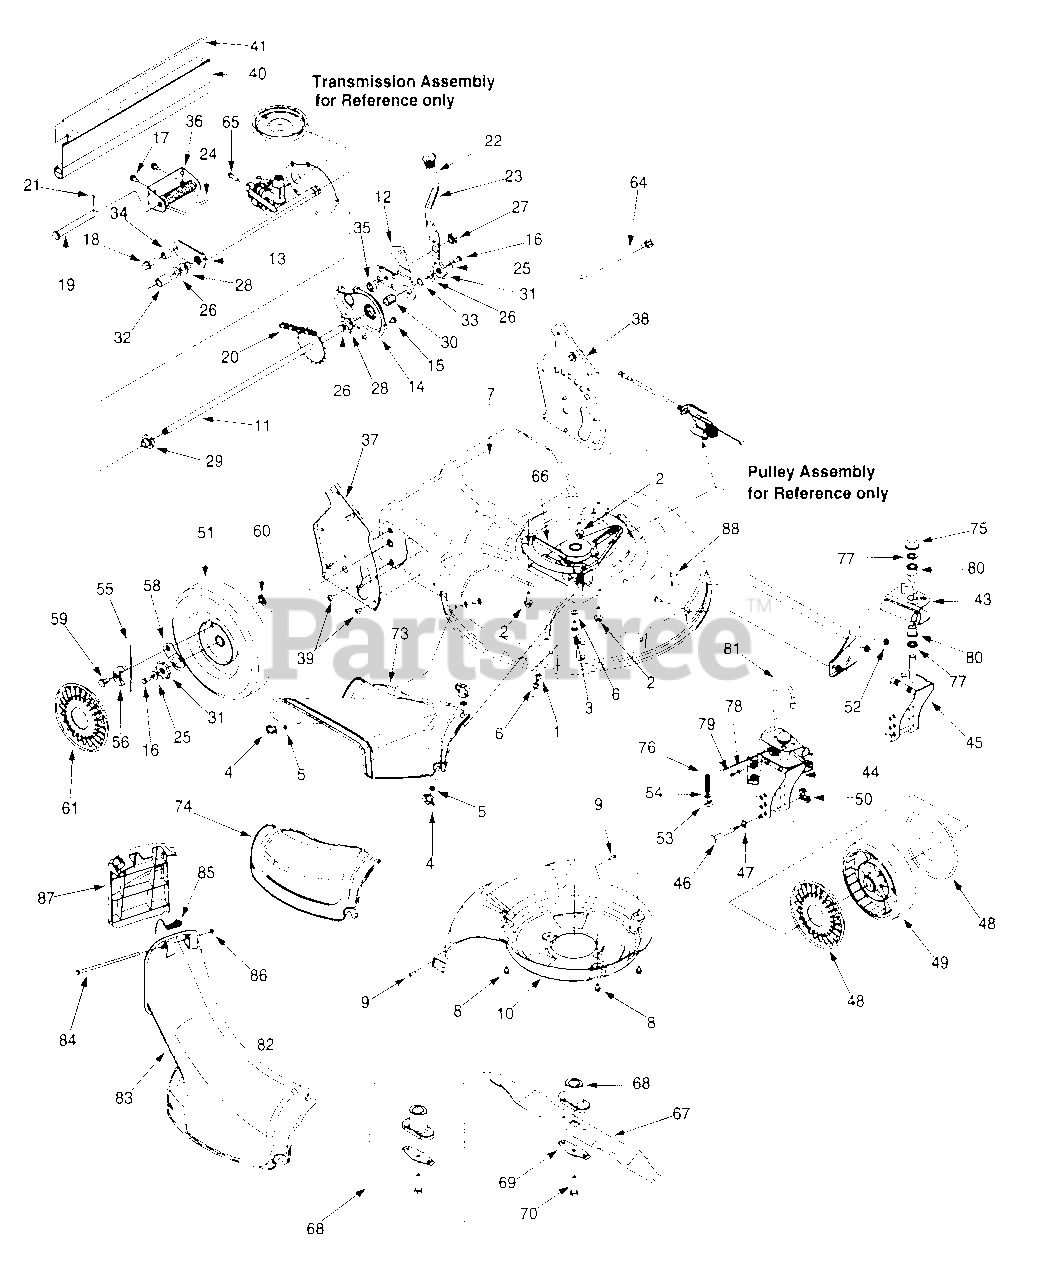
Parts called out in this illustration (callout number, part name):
1	Carriage Screw 1/4-20 x .62
2	Screw TT:3/8-18:1.00
3	Carriage Screw 1/4-20 x .750
4	Wing Nut 1/4-20
5	Push Nut .25 I.D. x .50 O.D.
6	Flat Washer .334 I.D.x .62 x.03
8	Screw TT. 1/4-20 x .375
9	Screw HL. 1/2-14 x .750
10	Baffle
11	Rear Axle Assembly
16	Cap Screw HH 1/4-20 x .620
17	Screw AB 1/4-20 x .625
18	Screw 3/8 116 x .25
19	Clevis Pin .50 Dia. x 4.82 Lg.
20	Chain #48 .500P x 24L
21	Cotter Pin .125O.D. x .75
23	Spring Lever
24	Torsion Spring
25	Bell Washer .285 x .75 x .082
26	Flat Washer .508 I.D. 1.000 x.020
27	Shoulder Nut .825 Dia. x .165 Lg.
28	Hex Flange Bearing .506 I.D. x .590 L.
29	Hex Flange Bearing .506 I.D. x .715 L.
30	Hex. Sleeve Bearing .504 I.D. x .830 L.
31	Wheel Rachet
32	Spacer .550 I.D. x /750 O.D.
33	Spacer .51 .D. x .70 O.D. x 38 L.
34	Spacer .385 x .624 x .700
35	Shoulder Spacer .385 I.D. x .715 Lg.
40	Trail Shield
41	Trail Shield Wire
46	Caster Axle .374 Dia x 2.50"
47	Wave Washer
48	Hub Cap w/ hole
49	Wheel 7 x 2 Link
50	Wing Nut 1/4-20
51	Wheel 9 x 2 Link
52	Lock Nut 5/15-18
53	Cotter Pin .072 x .12 Lg.
54	Flat Washer .330 x .830 x .060
55	Plastic Spring Ratchet
56	Pawl - R.H.
58	Ratchet Pawl Plate
59	Screw Shoulder .340 x .285
60	Top Lock Tab Weld Nut 1/4-20
61	Hubcap, w/o hole
64	Cable Tie
65	Hex Screw 5/16-18
66	Belt, 3/8"x 39.24"
67	21" Mulching Blade
68	Blade Adapter
69	Blade Bell Support
70	Hex Bolt 3/8-24 x 2.5"Lg.
73	Side Discharge Chute
74	Mulch Cover
76	Compression Spring
77	Flat Washer .5/8 I.D. x 1" O.D.
78	Flat Washer .203 x .403 x .040
79	Fitting - Grease
80	Flange Bearing
81	Locking Pin
82	Chute Ass'y
83	Discharge Chute
84	Pivot Rod
85	Torsion Spring
87	Chute Door
88	Carriage Bolt 5/16-18 x .62
